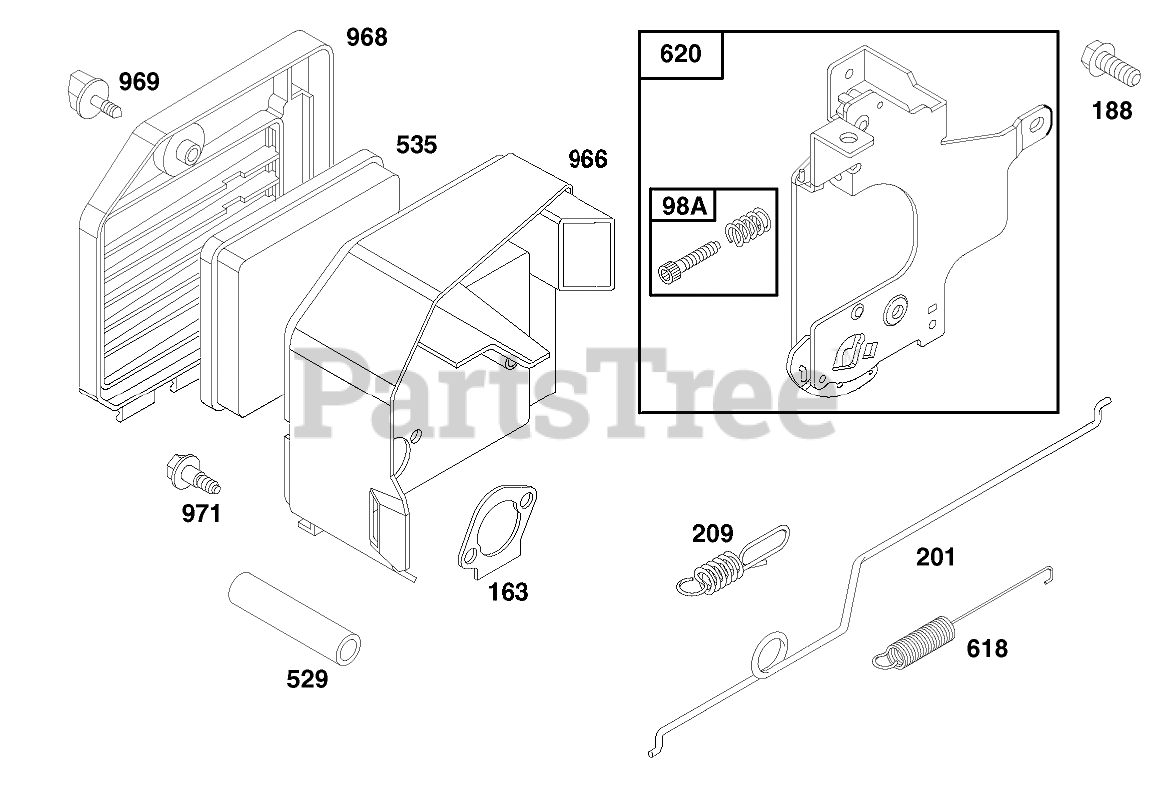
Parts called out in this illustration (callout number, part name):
98A	SPEED ADJUST. SCREW ASM
163	AIR CLEANER GASKET
188	Screw-Cap
201	GOVERNOR LINK
209	GOVERNOR SPRING
529	BREATHER TUBE
535	FILTER ELEMENT
618	RETURN SPRING
620	CARBURETOR BRACKET
966	AIR CLEANER BASE
968	AIR CLEANER COVER
969	AIR CLEANER SCREW
971	AIR CLEANER SCREW
